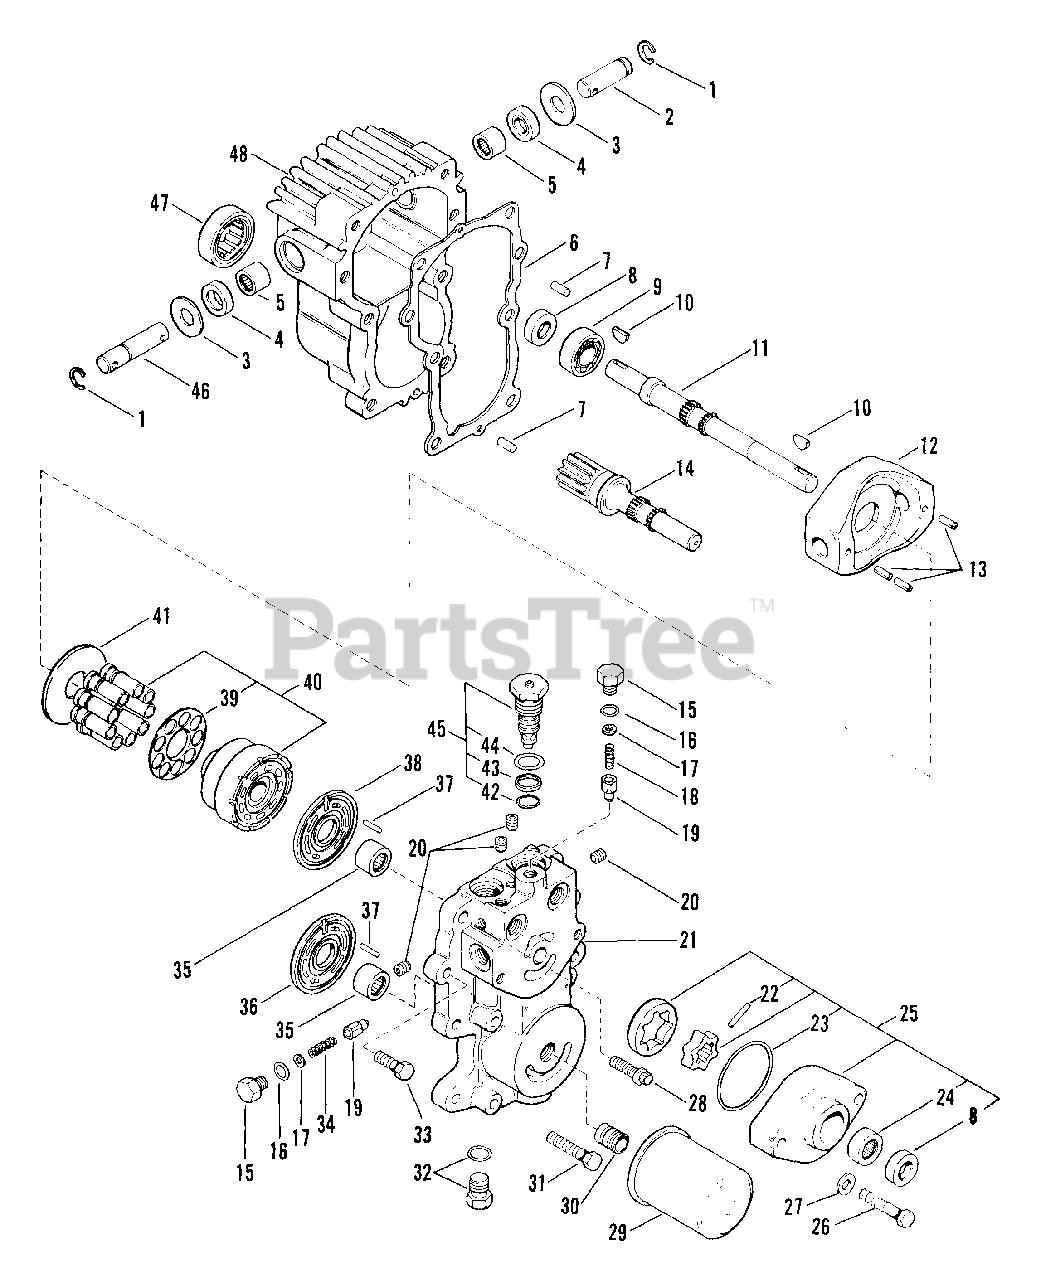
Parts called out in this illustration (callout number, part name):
1	RG-RTNG-EXT .688X.042
2	TRUNNION SHAFT
3	WSHR-FL-STL .699X1.375X.059
4	SEAL .625X1.187X.187
5	BRG-NEEDLE .688X.876X.63
7	DOWEL PIN
8	SEAL .625X1.128X.250
9	BRG-BALL 17MMX40MMX12MM
10	KEY-WDRF .188X.75X.313 SAE 9
11	PUMP SHAFT
12	SWASHPLATE VARIABLE
13	PIN-ROLL .188X.63
14	MOTOR SHAFT
15	PLUG-HEX HEAD
16	O-RING .414X.562X.072
17	SHIM PACKAGE
18	SG-COMP ??X??X?? SUNSTRAND
19	RELIEF VALVE CONE
20	PIPE PLUG
21	CENTER SECTION
23	O-RING 2.364X2.504X.072
24	BRG-NEEDLE .625X.875X.50
25	CHARGE PUMP ASSEMBLY
26	BLT-HEX .44-14X2.00 GR5
27	WSHR-FL-STL .469X.719X.108
28	SCR-12PNT .38-16X1.25 GR5
29	OIL FILTER
31	BLT-HEX .38-16X2.00 PL GR5
32	THREADED PLUG
33	BLT-HEX .38-16X1.50 PL GR5
34	SG-COMP ??X??X?? SUNSTRAND
35	BRG-NEEDLE 17MMX.938X.62
36	MOTOR VALVE PLATE
37	DOWEL PIN
38	VALVE PLATE
39	SLIPPER RETAINER
40	CYLINDER BLOCK KIT
41	THRUST PLATE
42	O-RING .614X.750X.070
43	O-RING .614X.750X.046
44	O-RING .770X.968X.097
45	CHECK VALVE ASSEMBLY
46	TRUNNION SHAFT
47	BRG-ROLLER 1.27X2.05X15MM
48	HOUSING W/SEALS AND BEARINGS
